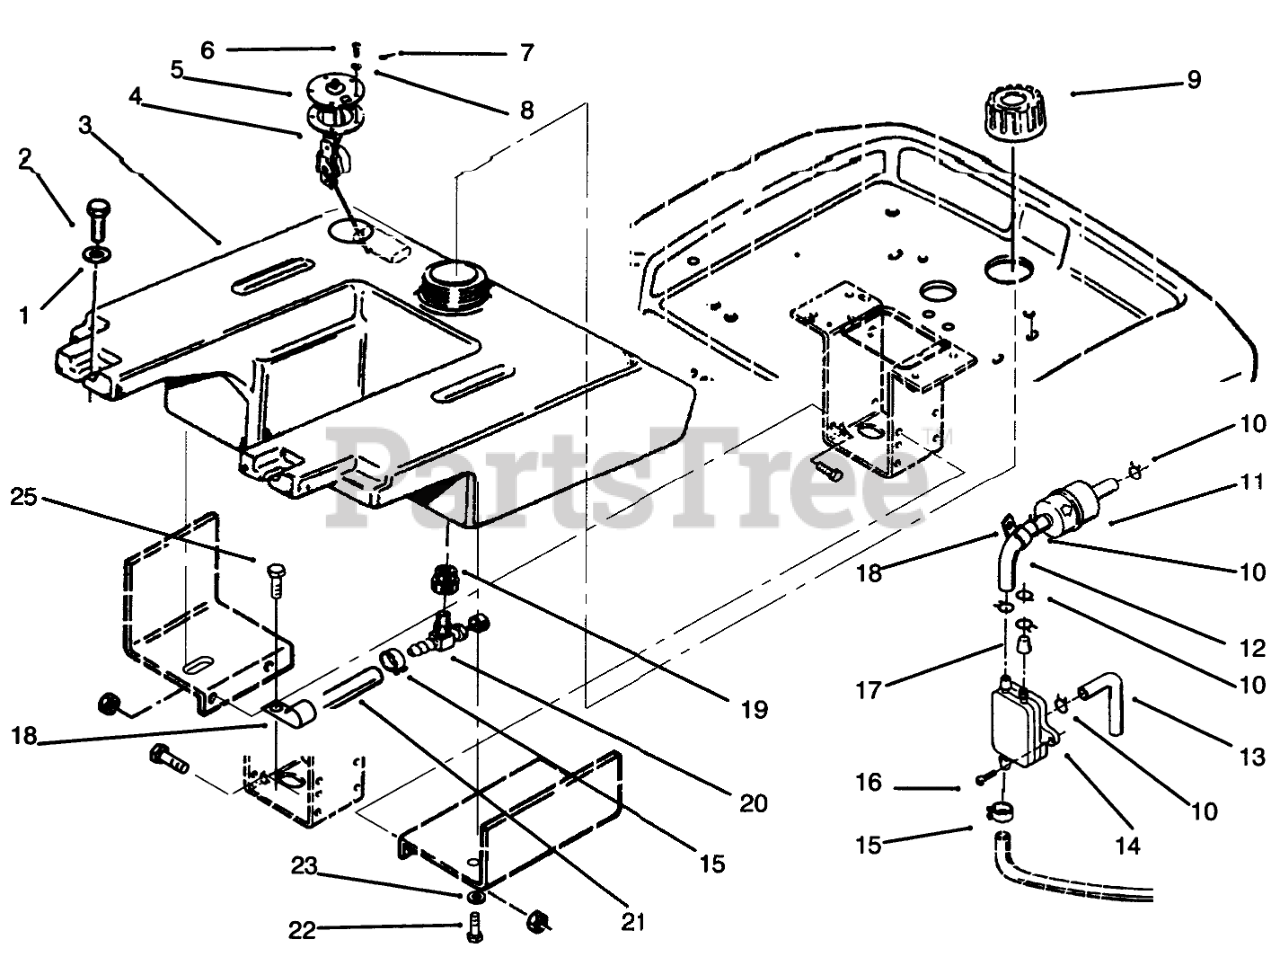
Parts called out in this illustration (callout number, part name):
1	WASHER-FLAT
2	SCREW-HWHTF
3	Tank-Fuel (Incl. Ref. #19 & 20)
4	GASKET-SENDER, FUEL
5	SENDER-FUEL LEVEL
6	Screw
7	TERMINAL-GROUND
8	WASHER-LOCK
9	GAS CAP ASM
10	CLAMP-HOSE
11	FILTER-FUEL
12	Hose
13	Hose
14	PUMP-FUEL
15	Clamp
16	SCREW-TAPPING PAN HD
17	Cap
18	Clamp
19	BUSHING
20	VALVE-FUEL
21	FUEL HOSE 75" OF 6554
22	SCREW-HH
23	WASHER-LOCK
25	SCREW-HH, LOCK
